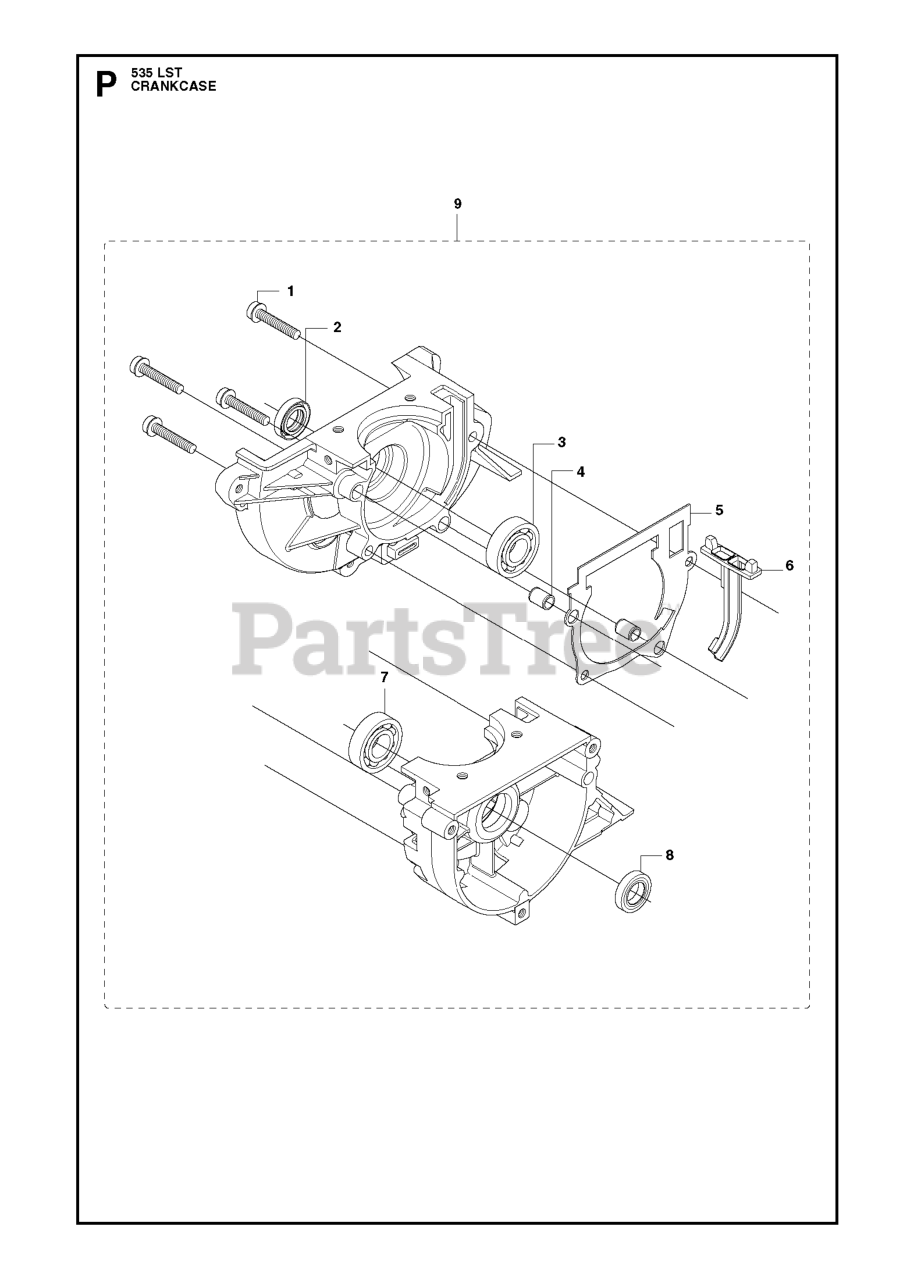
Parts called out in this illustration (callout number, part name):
2	SEALING RING
3	BALL BEARING
4	GUIDE BUSHING
5	GASKET CRANKCASE
6	INSERT, CARTER
7	BALL BEARING
8	SEALING RING
9	CRANKCASE CPL
